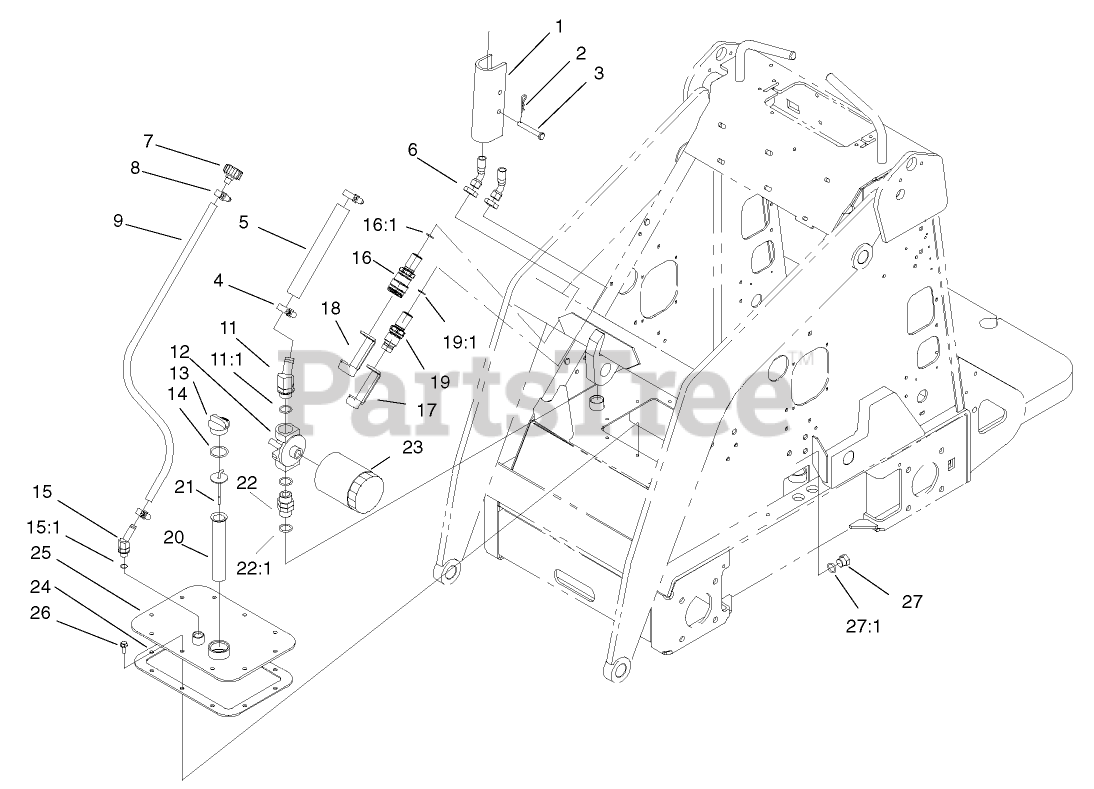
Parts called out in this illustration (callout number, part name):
1	LOCK-CYLINDER
2	PIN-HAIR
3	PIN-CLEVIS
4	CLAMP-HOSE
5	HOSE-SUCTION, HYD
6	NUT-LOCK, BULKHEAD
7	BREATHER
8	CLAMP-HOSE
9	HOSE-VENT
11	ELBOW-45 DEG
11:1	O-RING
12	HEAD-FILTER
13	PLUG-PLASTIC
14	O-RING
15	FITTING-HYD, 45 DEG
15:1	O-RING
16	BULKHEAD COUPLER ASM
16:1	O-RING
17	CAP-DUST, NIPPLE
18	CAP-DUST, COUPLER
19	BULKHEAD NIPPLE ASM
19:1	O-RING
20	FILTER-SCREEN
21	DIPSTICK-OIL
22	FITTING-THREAD, STRAIGHT
22:1	O-RING
23	FILTER-OIL, TRANSMISSION
24	GASKET-COVER
26	SCREW
27	PLUG-HEX
27:1	O-RING
